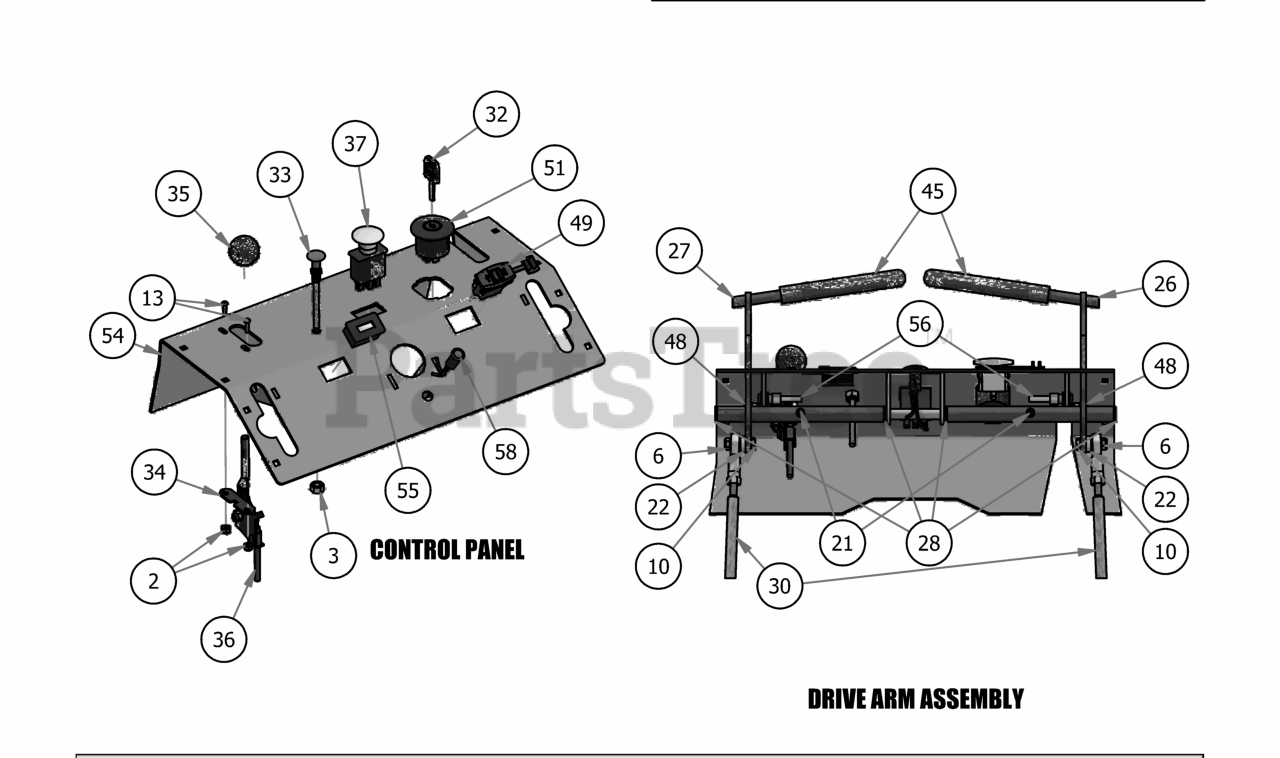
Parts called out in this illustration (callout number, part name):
1	1/4-20 Nylon Insert flange Nut
2	10-24 Nylon Insert Locknut Zinc Orange Nylon
3	3/8" Fine Threaded Jam Nut
4	5/16" Nylon Flange Nut
5	5/16" Flange Nut
6	5/16-18 Nylock Jam Nut 1/2 Nut
7	M6-1.0 X 16MM Hex Bolt
8	5/16" x 6" Carriage Bolt
9	12-24x 1/2 HWH Bolt
10	5/16 x 1 1/4 Hex Bolt
11	5/16" x 1 1/2" Carriage Bolt
12	3/8" x 1 1/4" Carriage Bolt
13	10-24 X 5/8 BS Button Head Bolt
14	3/8" x 1" Hex Bolt
15	5/16" x 1" Carriage Bolt
16	.390 x .750 x .062 Nylon Washer
17	3/8" Flat Washer
18	3/8" Lock Washer
19	.360 ID Plastic Washer
20	1/4" x 3/4" Carriage Bolt
21	1/4" Press in Grease Fitting
22	ACS Spacer 3/4x3/8x1/4
23	2019 Stand On Battery Hold Down
24	2019 Stand On Control Arm Stop Weldment
25	2019 Stand On Control Arm Stop Weldment_rear
26	2019 Stand On Drive Arm Actuator weldment_right
27	2019 Stand On Drive Arm Actuator weldment_left
28	2019 Drive Arm Bushing
29	Brake Spring
30	2019 Stand On Drive Push Rod Assembly
31	2019 Stand On Console Bracket Weldment
32	Ignition Key
34	Universal Throttle
35	Throttle Knob
36	Outlaw Throttle Cable
37	PTO Switch
38	Brake Cable
39	36" Red Battery Cable
40	Revolt EPA Cannister Assy
41	Hydro Tank Assembly
42	Interstate FAYTX14 Battery
43	8507A13 McMaster Carr Plunger
44	2019 Stand On Brake Handle
45	2019 Stand On Control Grip
46	Rubber Brake Grip-cZT/ZT 2013
47	2019 Stand On Waterbottle Cage
48	Magnet-Steering Arm-Stand On
50	Safety Switch
51	Ignition Switch
52	2019 Podium Panel Right
53	2019 Podium Panel Left
54	2019 Stand On Podium Front Panel Weldment
55	Tachometer
56	Safety Switch Harness
57	2019 Revolt Wiring Harness
57.1	Relay Terminal
